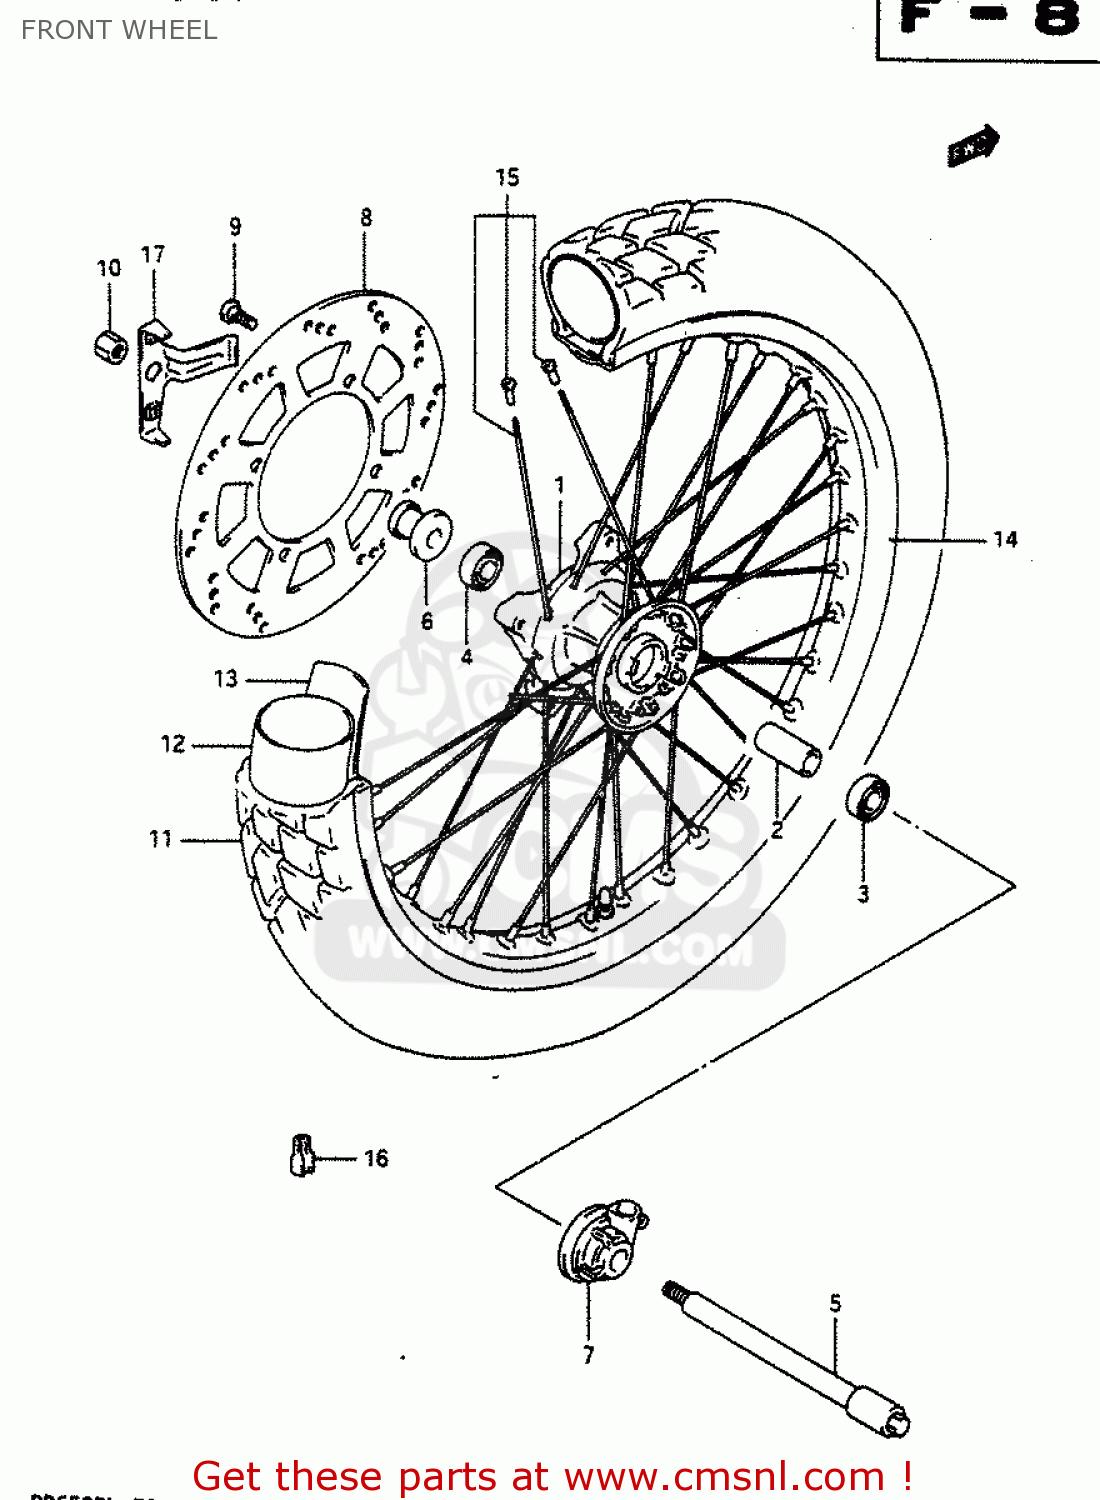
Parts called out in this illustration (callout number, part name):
1	HUB,FRONT WHEEL
2	SPACER,FR HUB BEARING
3	BEARING(15X32X15.9)
4	BEARING
5	AXLE,FR
6	SPACER,FRONT AXLE,LEFT
7	BOX ASSY,SPEEDOMETER GEAR
8	DISC,FR BRAKE
9	BOLT,BRAKE DISC
10	NUT
11	TIRE,FRONT
12	TUBE,INNER
13	PROTECTOR,WHEEL,INNER
14	RIM,FR WHEEL(21X1.85)
15	SPOKE SET,FR WHEEL
16	BALANCER,WHEEL
17	PLATE,PROTECTOR SET
